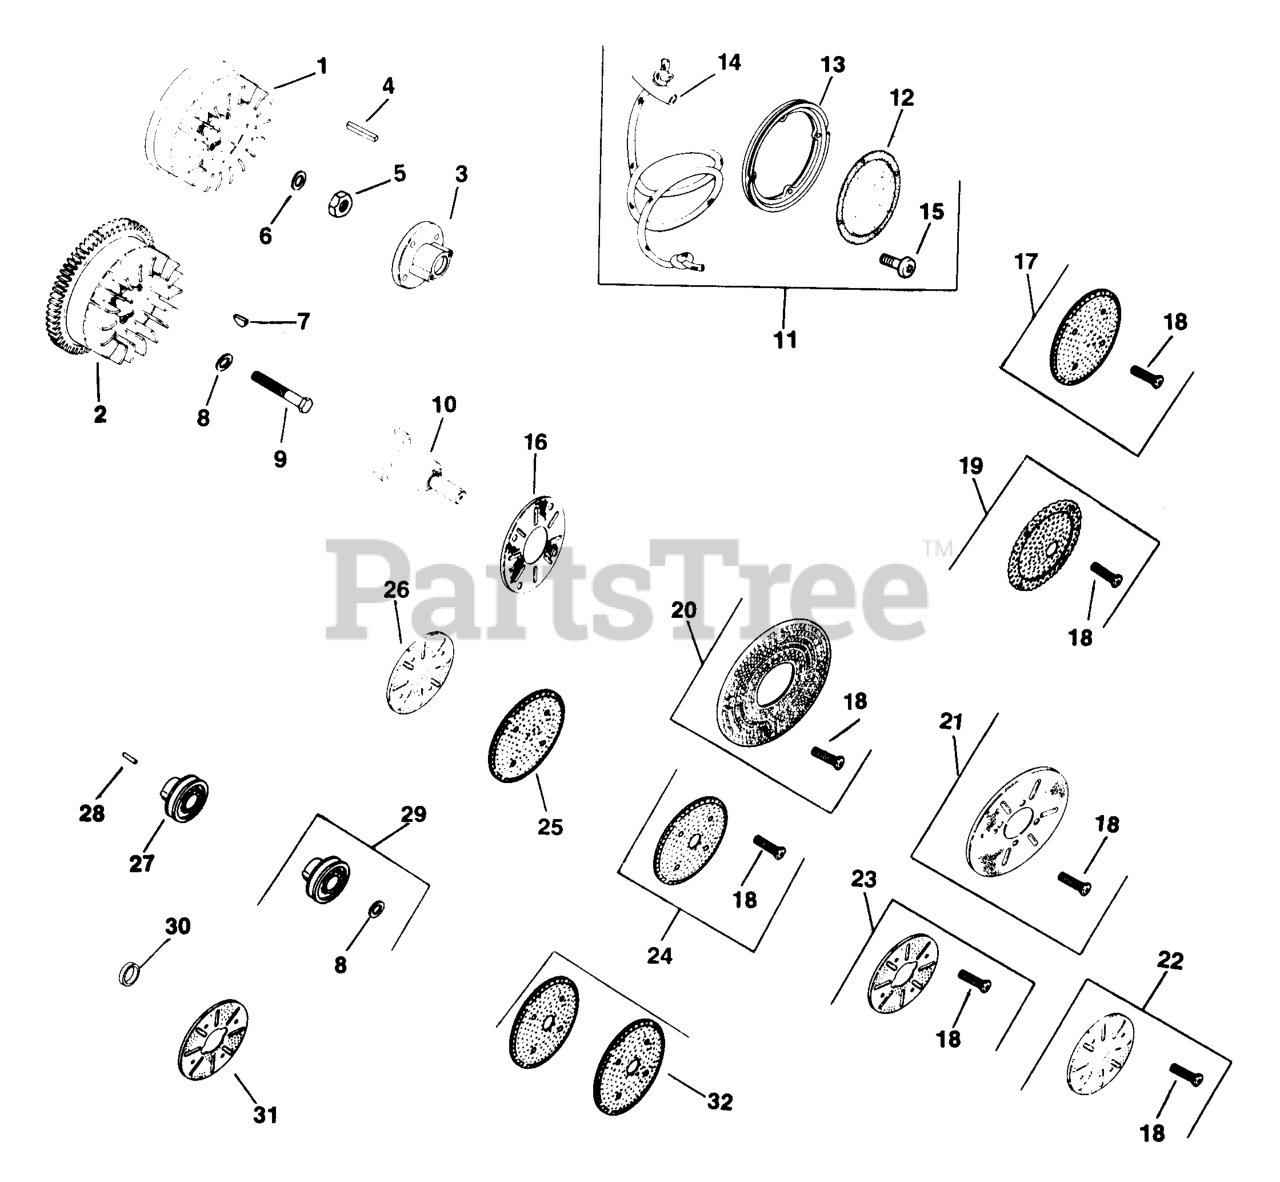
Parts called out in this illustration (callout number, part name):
5	NUT, 5/8 GRADE 2 - DISCONTINUED
6	WASHER - DISCONTINUED
7	KEY, 3/16" X 1"
8	WASHER (KM)-USE 12 468 03-S
9	SCREW, MACH 3/8-24X1-1/4"
14	ROPE-DISCONTINUED
19	KIT, GRASS SCREEN - DISCONTINUED
X-159-2-S	SCREW, SEMS 3/8-16-X1"
